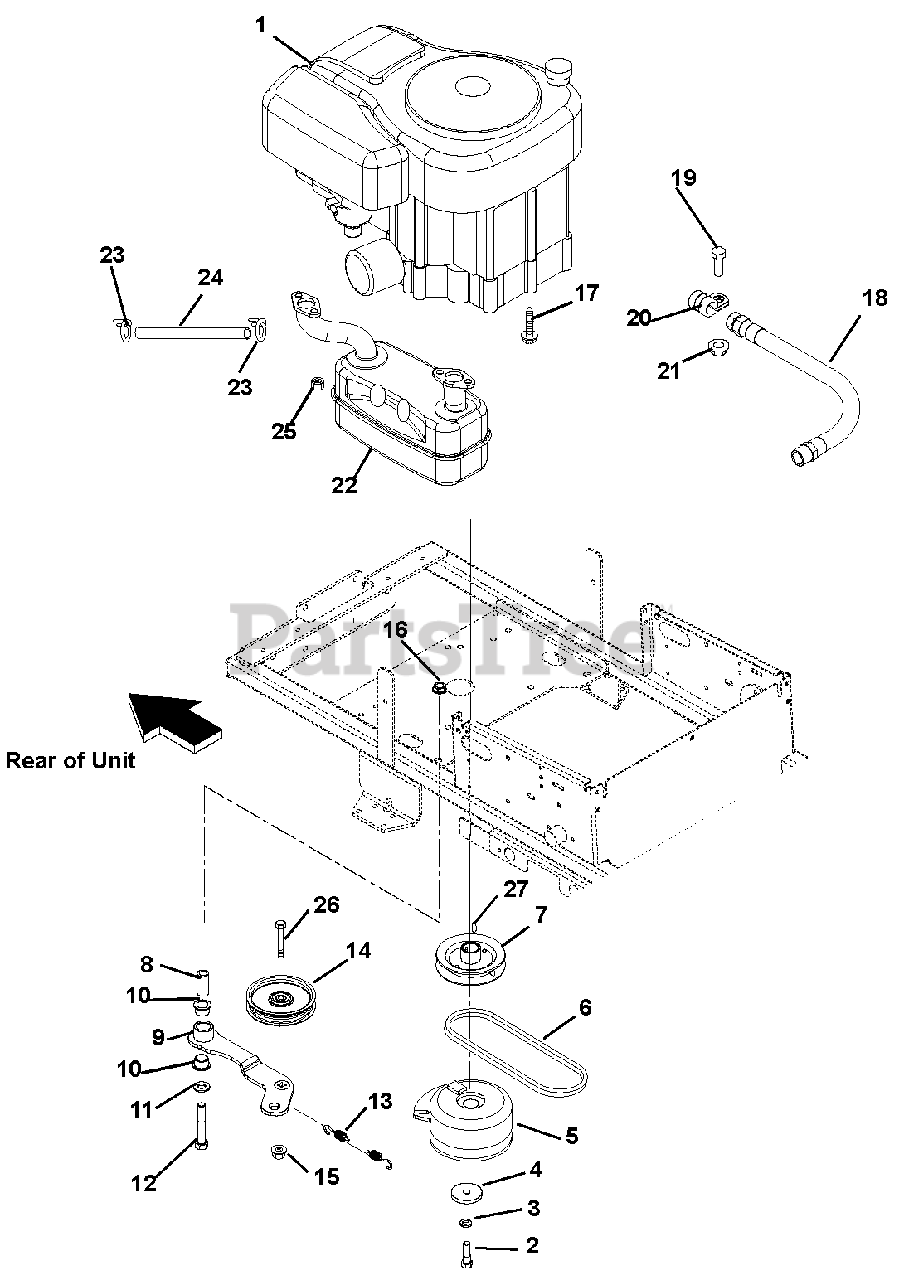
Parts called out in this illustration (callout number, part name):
1	Engine, 20HP Single Kohler (403)
2	7/16 - 20 x 3-1/4 HHCS Grade 8
3	Washer, Locking .44 x .109 Regular
4	Washer, Flat Steel .469 x 2.00 x .25
5	Electric Clutch (404)
6	V-Belt, A-RMAX x .50
7	Pulley, V 3.75X1.0 A Section with Key
8	Bushing, Sleave .500 x .750 x .1.560
9	Weldment, Idler
10	Bushing, Flange 0.75 x 0.875 x .625 x 1.125
11	Washer, Flat Steel .531 x 1.06 x .095
12	Bolt, Hex .50-13 x 3.25
13	Spring, Extension
14	Idler, Flanged 4.00
15	Nut, 3/8-16 Flange Nyloc
16	Nut, Locking Top Flange .50-13
17	Bolt, Hex .31-18 x 1.75 Grade 5
18	Hose Assembly, Oil Drive .38 x 11.5 OAL
19	Bolt, Hex .31-18 x .75 Grade 5
20	Clamp, Cushioned Steel .75
21	Nut, .31-18 Nyloc Flange
22	Muffler, Twin Kohler (404)
23	Clamp, Hose Wire .490/.510 x .092
24	Gas Line, Bulk 28" LG
25	Nut, Top Lock Flange 8 x 1.25 (404)
26	Bolt, Hex .38-16 x 2.00 Grade 5
27	Key, Square .25 x 1.00 x .25 (included with part #7)
